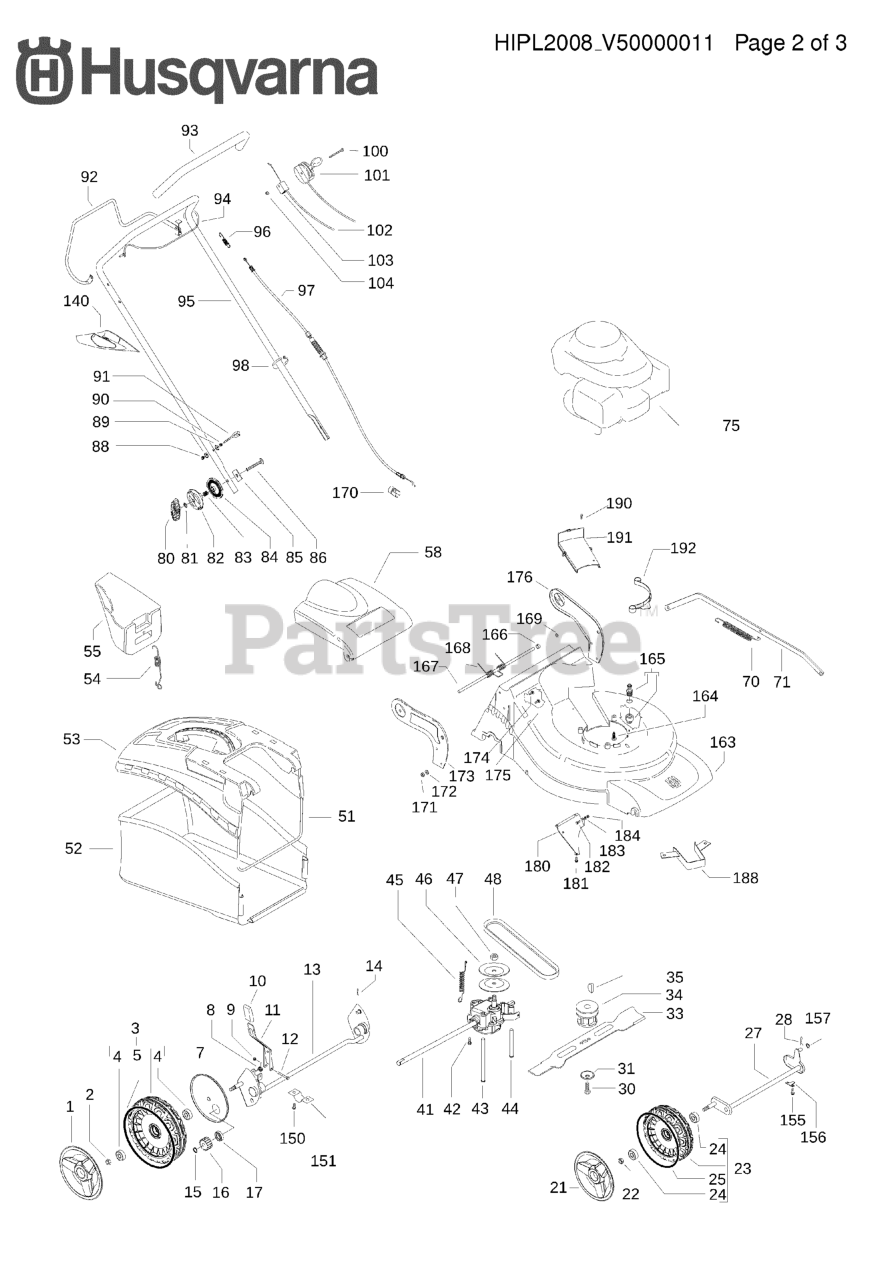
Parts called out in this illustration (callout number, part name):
11	LIFTING LEVER ASSY FOR REAR AX
51	FRAME 51 CAST
53	COVER HARD TOP
58	DEFLECTOR 51 CAST ORANGE
102	BRAKE WIRE
168	SPRING 51 CAST
